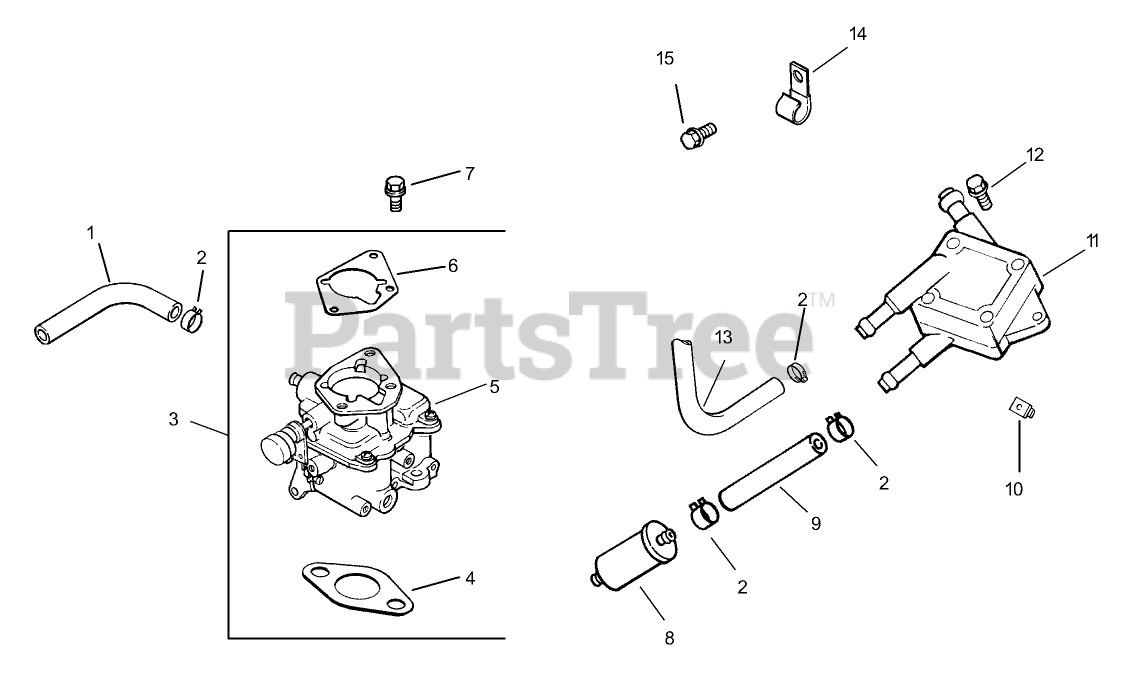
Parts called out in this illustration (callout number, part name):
1	Line-Fuel (9.5)
2	CLAMP-HOSE, SPRING (1/2)
3	Kit, carburetor w/gasket (Includes 4-6)
4	Gasket-Carburetor
5	Carburetor assembly (For information only, not available separately)(Service with kits 24 757 01-S, 24 757 02-S, 24 757 03-S, 24 757 07-S, 24 757 08-S, and 24 757 09-S)
6	GASKET-BASE, AIR CLEANER
7	SCREW-FLANGE (M6X1.0X30)
8	Filter-Fuel
9	Line-Fuel (3.5)
10	Nut-Plastic
11	PUMP-FUEL
12	SCREW-TAP (M6X1.7X18)
13	Line-Fuel, Flexible (15.5)
14	CLIP-CABLE
15	Screw-HF (M6x1.0x12)
